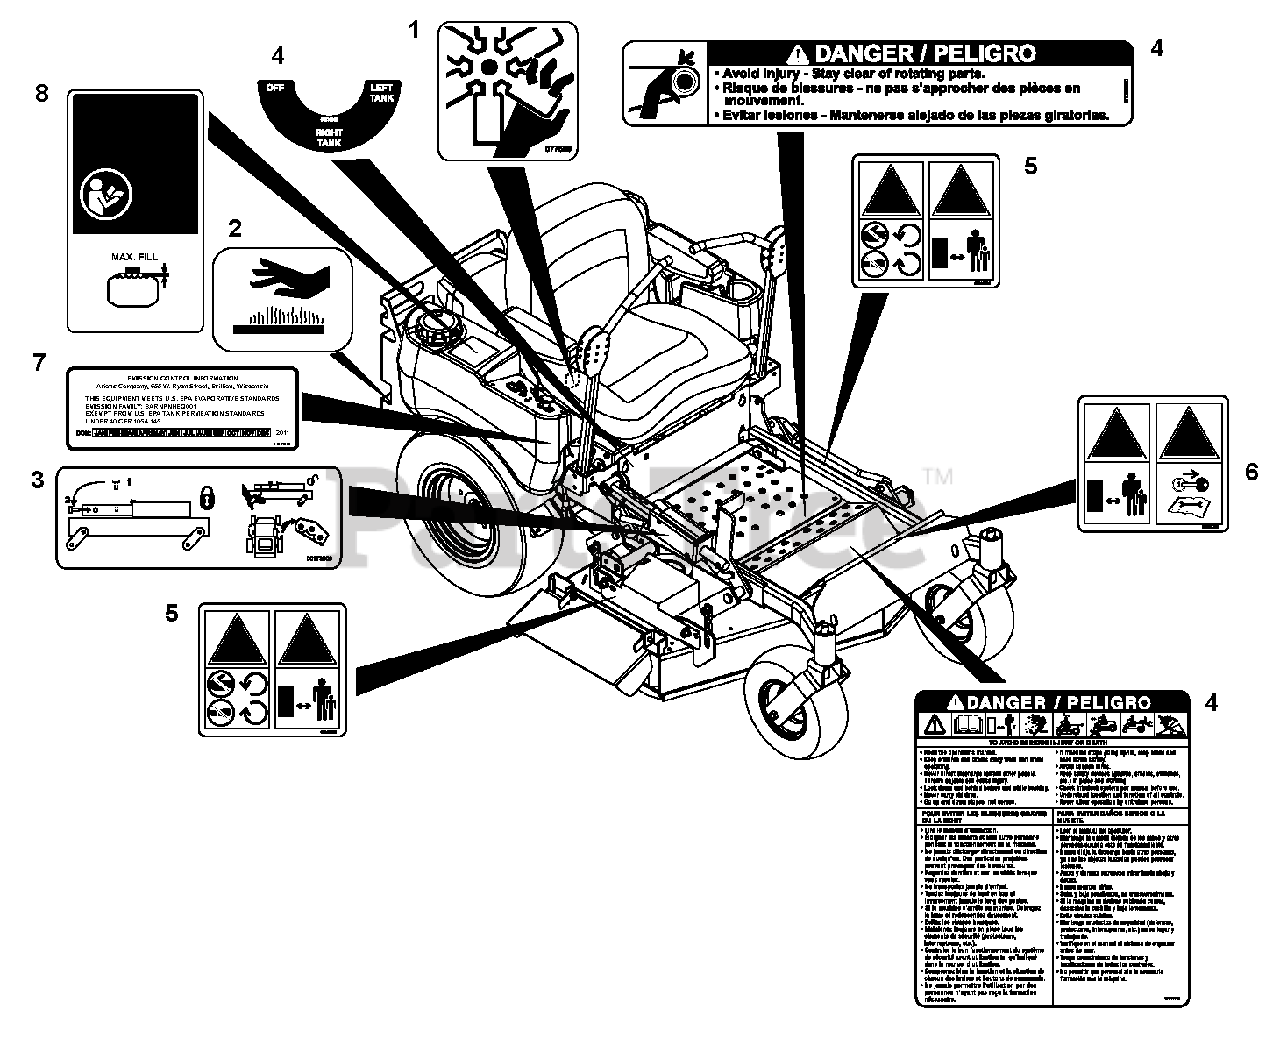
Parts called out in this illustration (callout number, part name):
1	Decal, Danger Fan
2	Decal, Hot Surface
3	Decal, Deck Service
4	Set, Decal Common Danger/Fuel
5	Decal, CE Deck
6	Decal, CE Caution
7	Label, EPA Non-Compliant Tank
8	Decal, Fuel Warning
